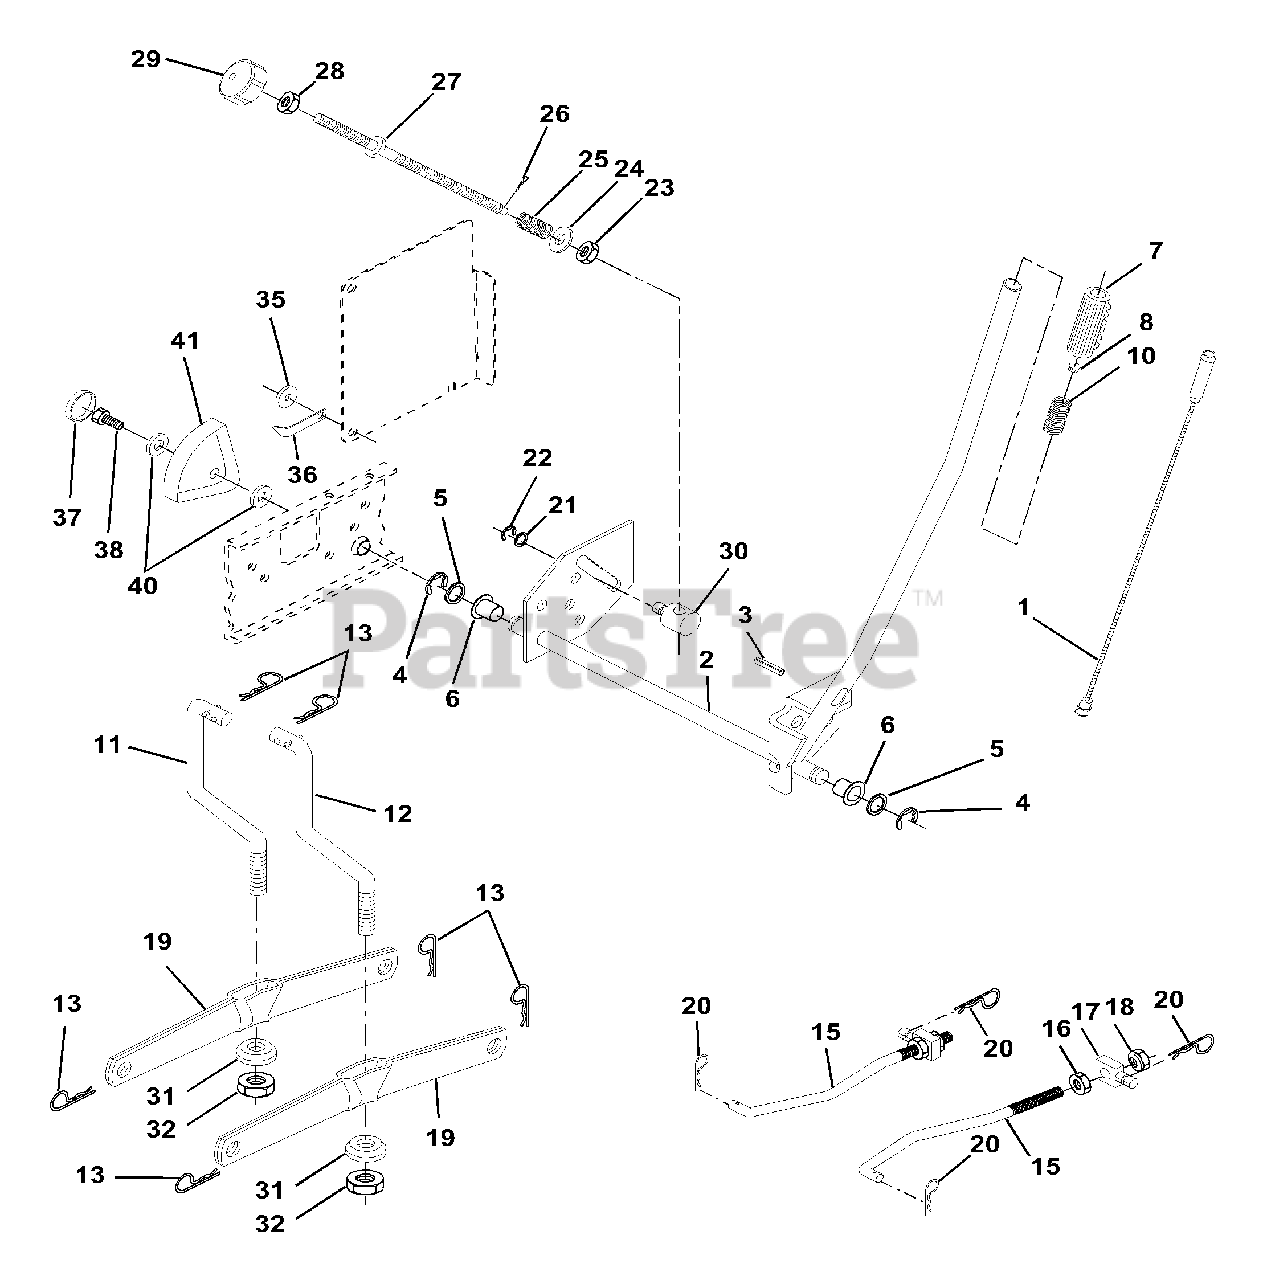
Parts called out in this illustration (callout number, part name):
1	Wire Asm Inner W/plunger 17 32
2	Shaft Asm Lift 93 RH
3	Pin Groove 1 500 Zinc
4	E Ring #5133-62
5	Washer 21/32 X 1 X 21 Ga
6	Bearing Nylon Blk 629 Id
7	Grip Handle Fluted Blk
8	Button Plunger Black
10	Spring Cprsn 3 750 Oiled
11	Link Lift LH
12	Link Lift RH
13	Retainer Spring
15	Link Front
16	Nut Jam Hex 1/2-13 Unc
17	Trunnion Blk Zinc
18	Nut Lock W/wsh 1/2-13unc
19	Arm Suspension Rear
20	Retainer Spring
21	Washer 15/32 X 3/4 X 16 Ga
22	Ring Klip #t5304-37
23	Nut Special
24	Washer 13/32 X 5/8 X 16 Ga
25	Spring 2-1/8"
26	Pin Cotter 3/32 X 1/2
27	Rod Adj Lift Zinc 9 00 Wrk Lg
28	Nut Hex Jam 3/8-16 Unc
29	Knob Inf 3/8-16 Unc Blk W/sym
30	Trunnion Dp Stop Dbl Thds PLT
31	Bearing pvt. Lift Sphencal
32	3/8-24 Nylock Nut
35	Washer Nylon .44 x .75 x 032
36	Pointer pnt height ind.
37	Plug hole Blk 1.485/1.515 Dia
38	Screw Thdrol 5/16-18 x 3/4 Tyt
40	Washer 11/32 x 1-1/2 10 Ga
41	Scale Ind. Hieght Black
